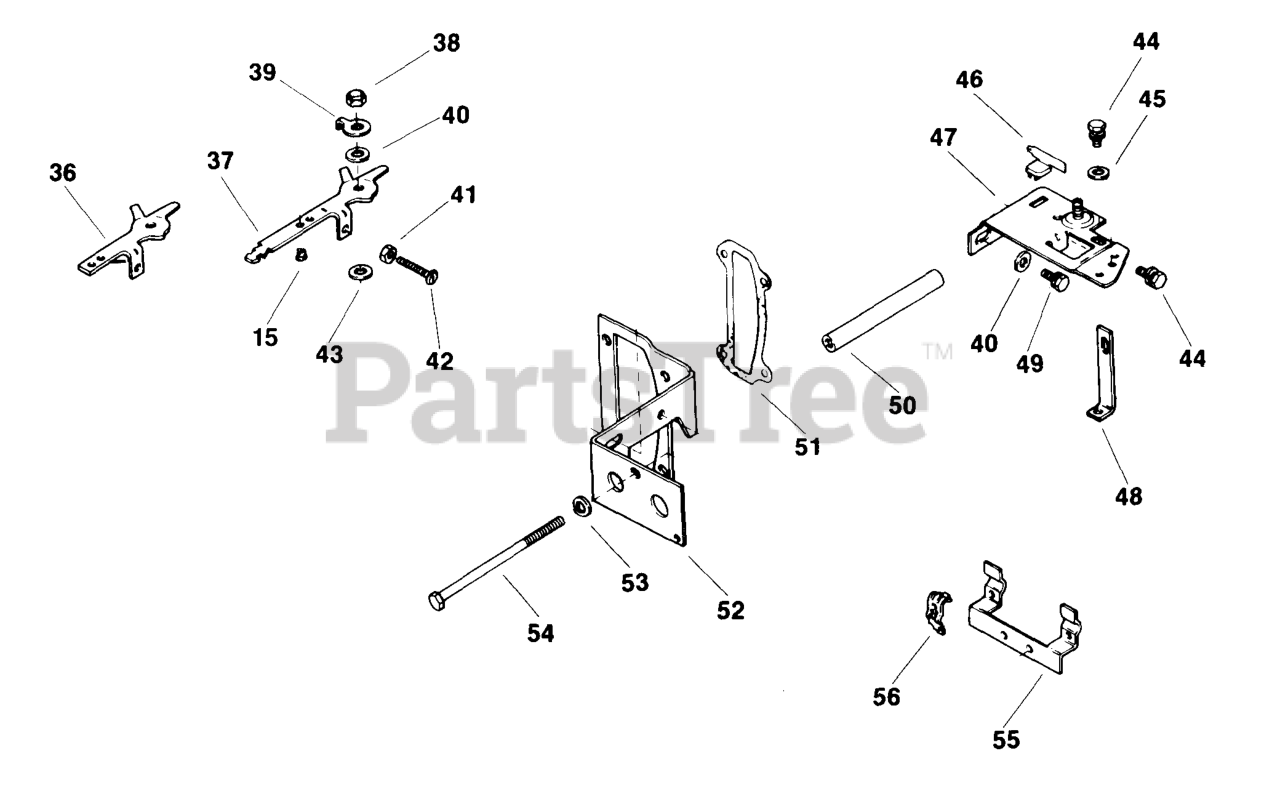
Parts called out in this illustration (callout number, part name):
15	BUSHING-DISCONTINUED
45	WASHER, FLAT 1/4" (O.D. 1/2")
53	WASHER, SPRING LOCK 1/4"
